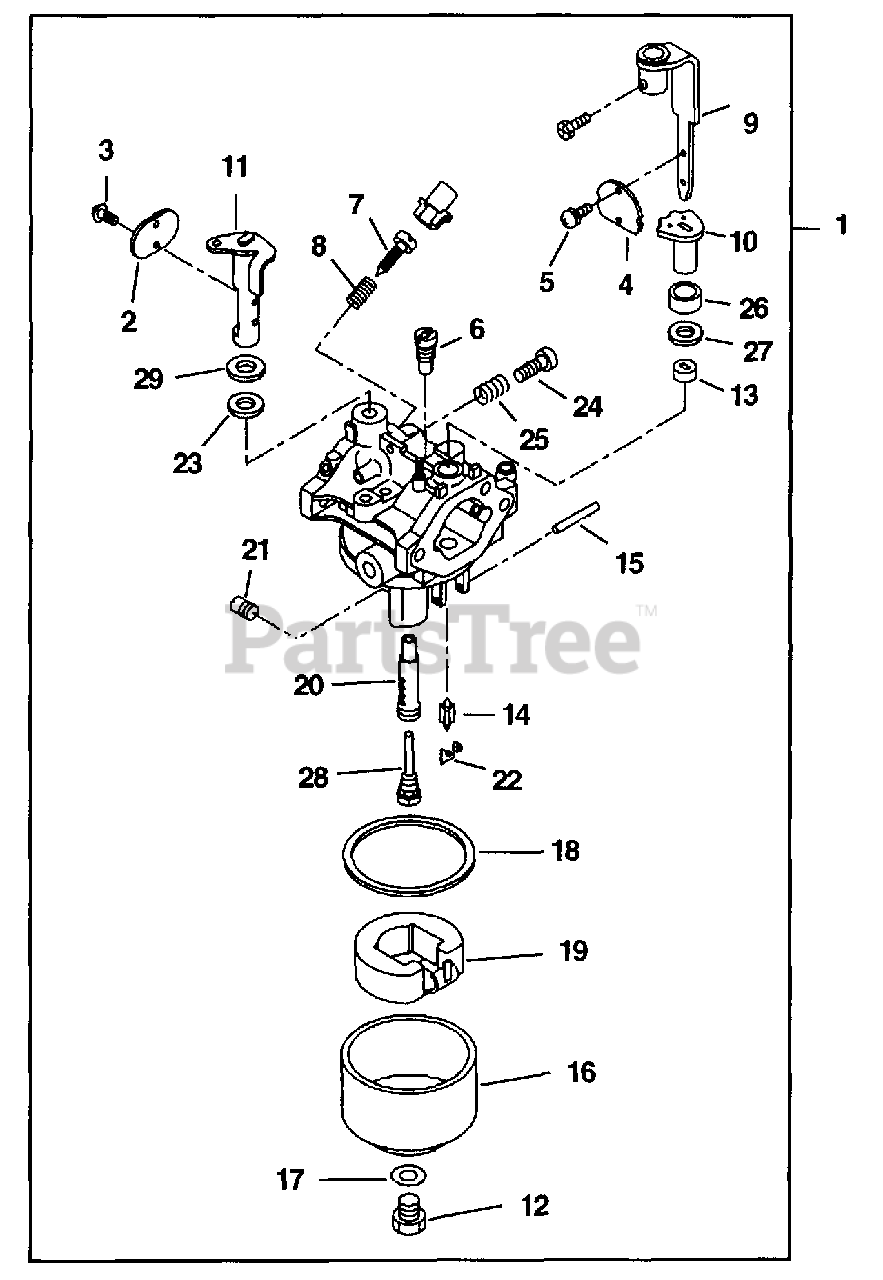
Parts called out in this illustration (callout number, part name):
1	Carburetor
2	Throttle valve
4	Choke valve
5	Panhead screw
6	Pilot jet
7	Adjuster
9	Choke lever
11	Throttle shaft
12	Bolt
14	Needle valve
15	Float pin
16	Float chamber body
17	Insert washer
18	Chamber packing
20	Main nozzle
21	Main jet
24	Adjusting screw
28	Guide holder
